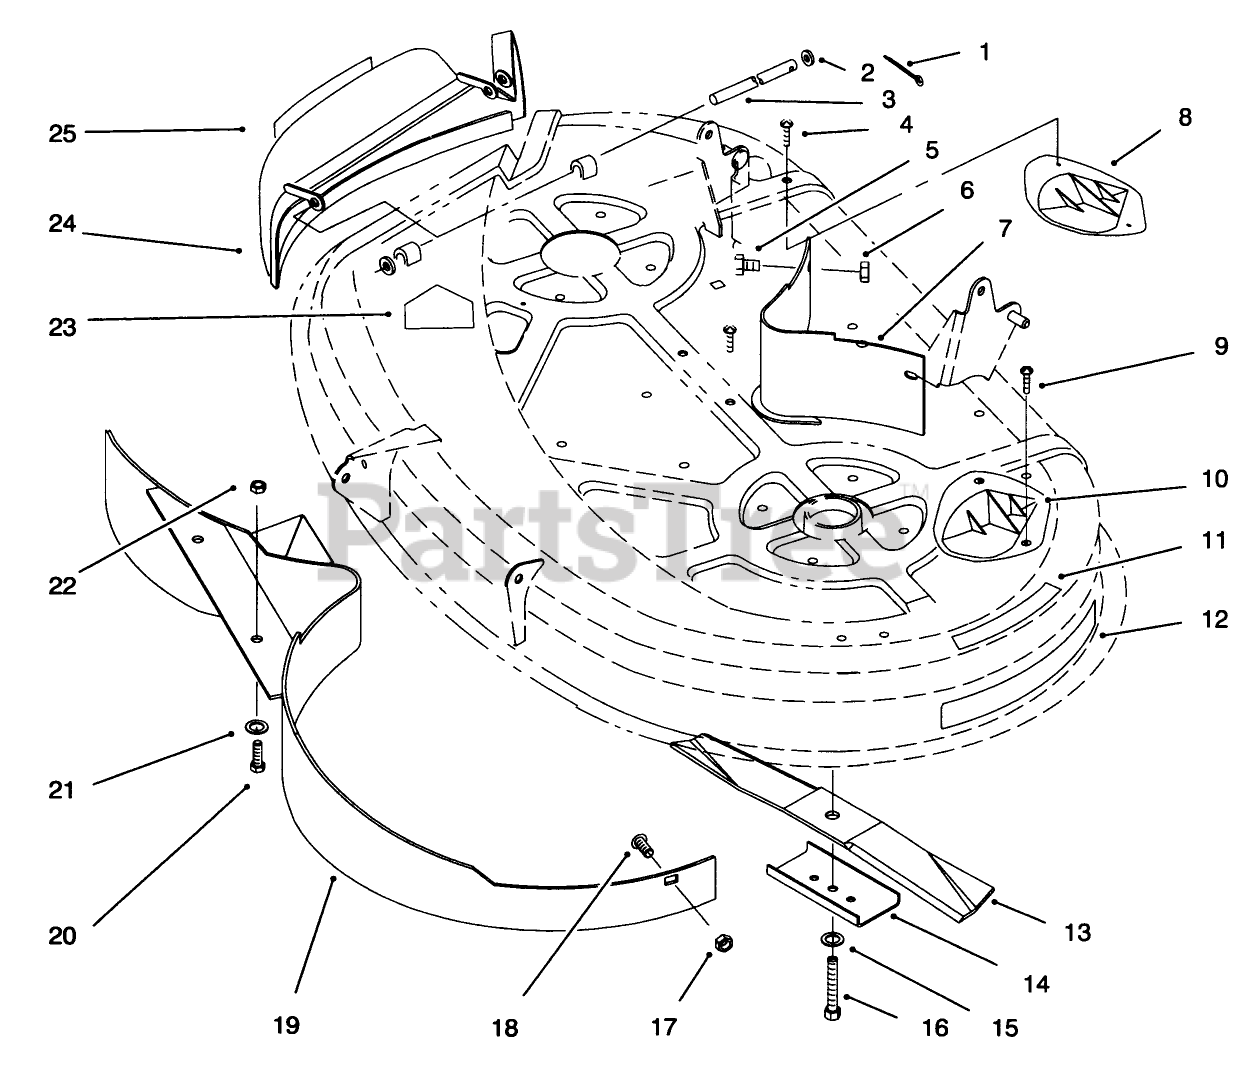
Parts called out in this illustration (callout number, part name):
1	PIN-COTTER
2	WASHER-PLAIN
4	SCREW-PPH, PLASTITE
5	SCREW-HH
6	NUT-LOCK, NI
7	Baffle-Rear
8	KICKER
9	#8 X .625" PHILPS PAN H
10	PLATE-KICKER
11	DECAL-DANGER
12	DECAL-RECYCLER
13	BLADE KIT
14	Stiffener
15	Washer (Ref.)
16	Bolt (Ref.)
17	NUT-LOCK, NI
18	BOLT-CARR
19	Baffle-38"
20	SCREW-HH
21	WASHER
22	NUT-LOCK, NI
23	DECAL-DANGER
24	Chute-Recycler
25	DECAL-DANGER, THROWN OBJECT
